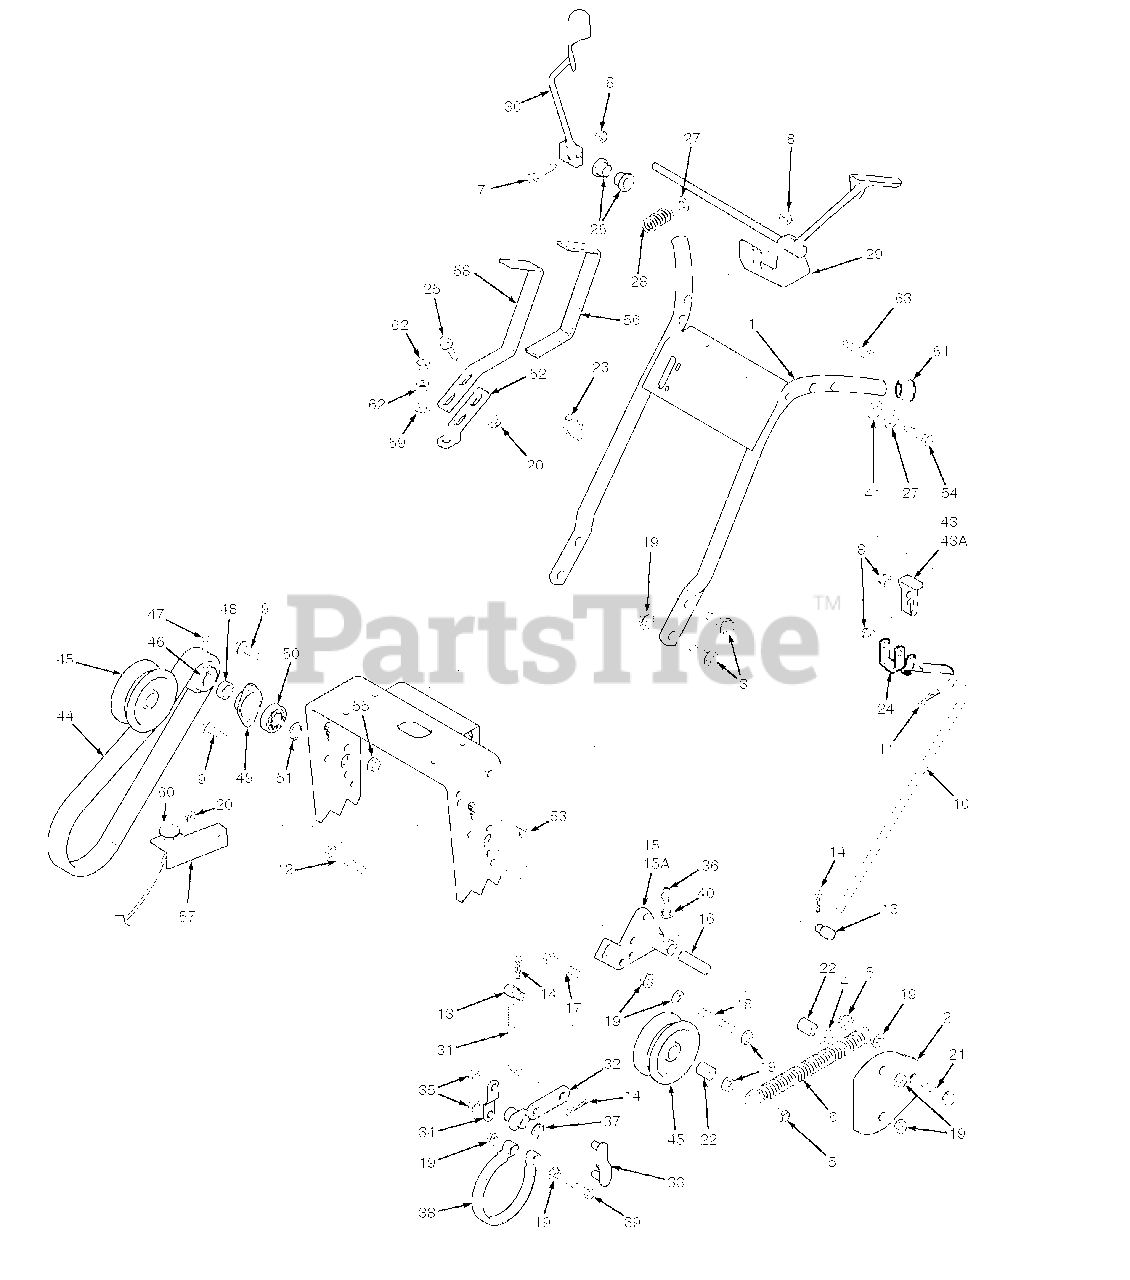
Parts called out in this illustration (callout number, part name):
1	Handle Assembly
2	Belt Guard
3	Capscrw, 3/8-16 x 1" Serr. Flg.
4	Washer, 3/8" (.391 x .938 x .105)
5	Nut, 3/8-16 Elastic Stop
6	Spring, Idler
7	Bolt, 5/16-18 x 1-1/4" Hex Head
8	Nut, 5/16-18 Elastic Stop
9	Capscrew, 1/4-20 x 3/4" Hex Head
10	Control Rod, Steering
11	Hair Pin, Small
12	Bolt, 3/8-16 x 4-1/2" Hex Head
13	Swivel Joint
14	Hair Pin, Large .094 Dia.
15	Idler Bracket, RH
15A	Idler Bracket, LH
16	Idler Sleeve
17	Bolt, 3/8-16 x 3/4" Hex Head
18	Stud, 3/8-16 x 5"
19	Nut, 3/8-16 Serrated Flange
20	Nut, 5/16-18 Serrated Flange
21	Cpscrw, 3/16-18 x 1-1/4" Serr. Flg
22	Spacer
23	Cable Tie
24	Steering Lever
25	Capscrew, 5/16-18 x 1" Serr. Flg.
26	Bushing
27	Washer, 5/16 (.375 x .875 x .083)
28	Spring, Operator Presence
29	Operator Presence Lever, LH
30	Operator Presence Lever, RH
31	Brake Rod
32	Brake Lever
33	Brake Link
34	Brake Link Plate
35	Nut, 3/8 Push-on
36	Grease Fitting, Straight 1/4-28
37	Retaining Ring, 5/8 Ext. "E"
38	Brake Band
39	Bolt, 3/8-16 x 2" Hex Head
40	1/4" Internal Tooth Lockwasher
41	Socket Head Capscrew #8-32 x 1/2"
42	Socket Head Capscrew #8-32 x 1/2"
43	Neutral Latch, RH
43A	Neutral Latch, LH
44	Belt, Wheel Drive
45	Idler Pulley, Wheel Drive
46	Pulley, Jackshaft
47	Setscrew, Hex Socket Knurl Cup Pt. 5/16-18
48	Spacer, Jackshaft Pulley
49	Flange, Jackshaft Bearing
50	Bearing, Jackshaft
51	Retaining Ring, 5/8 Ext. Basic
52	Shift Lever
53	Capscrew, 5/16-18 x 3/4" Serr. Flg.
54	Bolt, 5/16-18 x 2" Hex Head
55	Nut, 1/4-20 Serrated Flange
56	Grip, Shift Handle
57	Bracket, Choke Mounting
58	Shift Lever Extention
59	Washer, 3/8 (.391x .938 x .105)
60	Choke Control
61	Plug, Handlebar
62	Nut, 3/8-24 UNF
63	Bolt, 5/16-18 x 2-1/2"
64	Fuel Tank Cap
